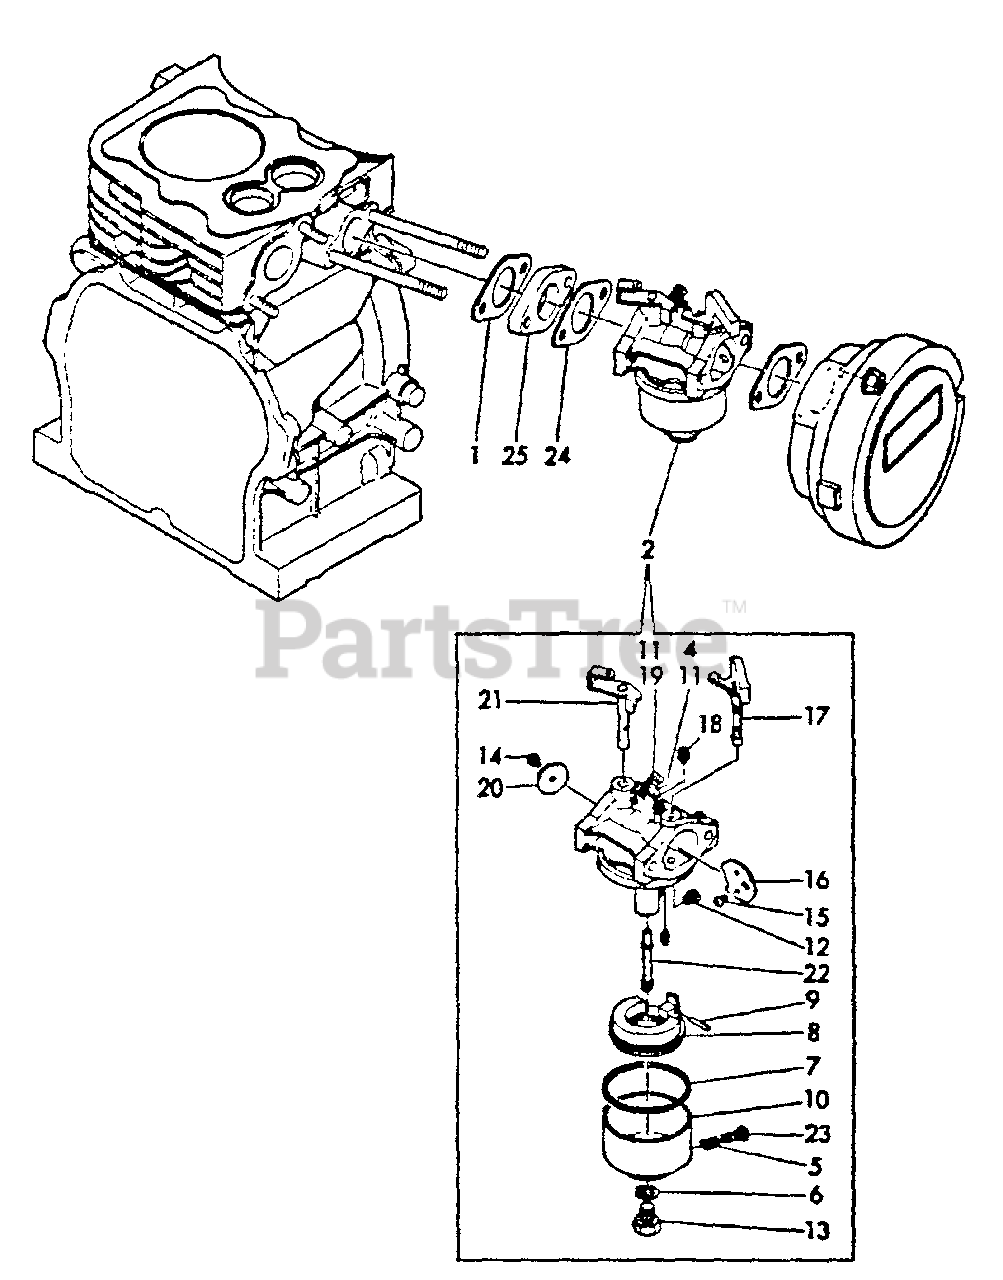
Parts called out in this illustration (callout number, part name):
1	GASKET, EXHAUST
2	CARBURETOR
4	SCREW
6	GASKET
7	GASKET
8	FLOAT
9	PIN
10	BODY, FLOAT CHAMBER
11	SPRING
12	JET, MAIN
13	BOLT
14	SCREW
15	SCREW
16	VALVE, CHOKE
17	SHAFT, CHOKE
18	JET, PILOT
19	SCREW
20	VALVE, THROTTLE
21	SHAFT ASSY, THROTTLE
22	NOZZLE, MAIN
23	SCREW
24	GASKET, INTAKE
25	GASKET
